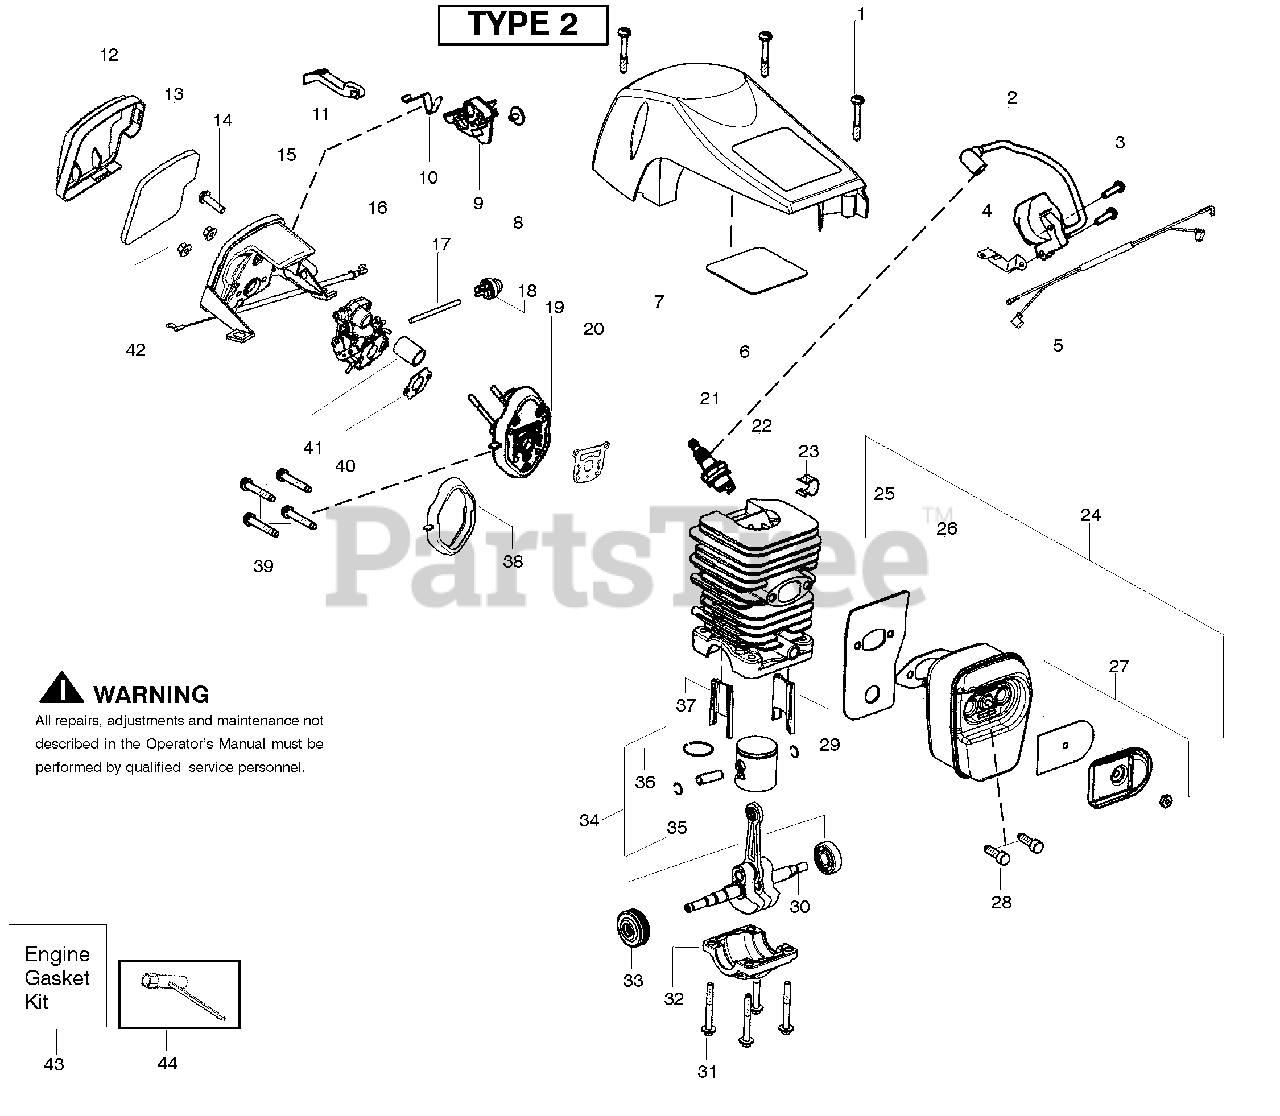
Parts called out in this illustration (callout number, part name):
2	Module-Ignition
4	Strap-Ground
5	Assy-Wire Harness
6	Reflector-Tape
7	Shield-Cylinder
9	Lever-Ignition Switch
10	Spring-Ignition Switch
11	Knob-Choke
12	Cover-Air Filter
13	Filter-Air
15	Housing-Air Filter w/cable
16	Carburetor Zama W26
17	Kit-Fuel Line (Small)
18	Bulb-Purge "snap-in"
19	Kit-Carb. Adaptor
20	Gasket-cyl. o-ring (kit)
21	Accy-Spark Plug (RCJ-7Y)
22	Kit-Cylinder
23	Clip-High Tension Lead
24	Kit-Muffler
25	Backplate-Muffler
26	Gasket-Muffler (kit)
27	Kit-Spark Arrestor
28	Bolt-Muffler
29	Insert-Left (black) Cyl.
30	Assy-Crankshaft/Rod
32	Cap-Crankcase
33	Assy-Bearing/Seal
34	Kit-Piston
35	Retainer-Piston Pin
36	Ring-Piston
37	Insert-Right (gray)Cyl.
38	Seal-Adaptor (kit)
40	Gasket-Carb. (kit)
41	Tube-Intake
42	Nut-Carb.
43	Kit-Gasket
